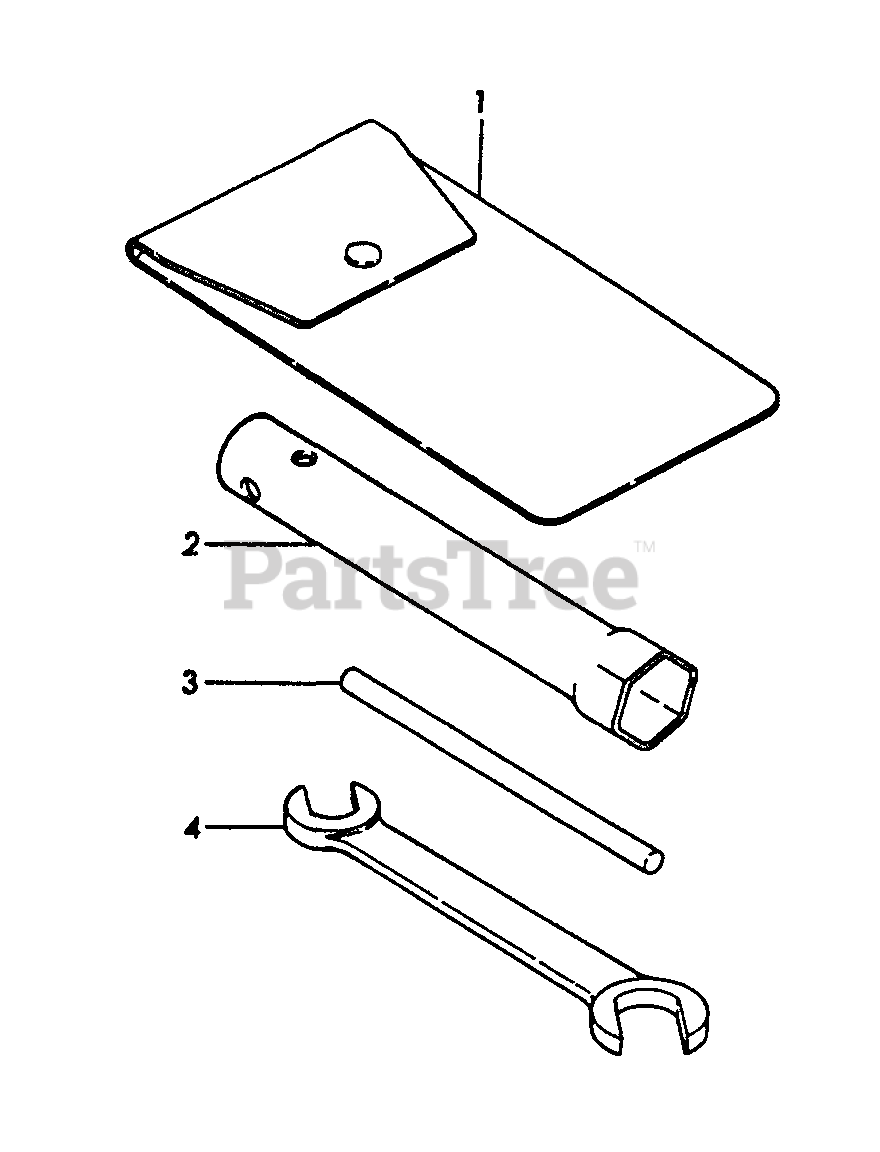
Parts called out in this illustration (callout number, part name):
1	BAG, TOOL
2	SOCKET WRENCH - 21mm
3	BAR
4	SPANNER - 10X12mm
